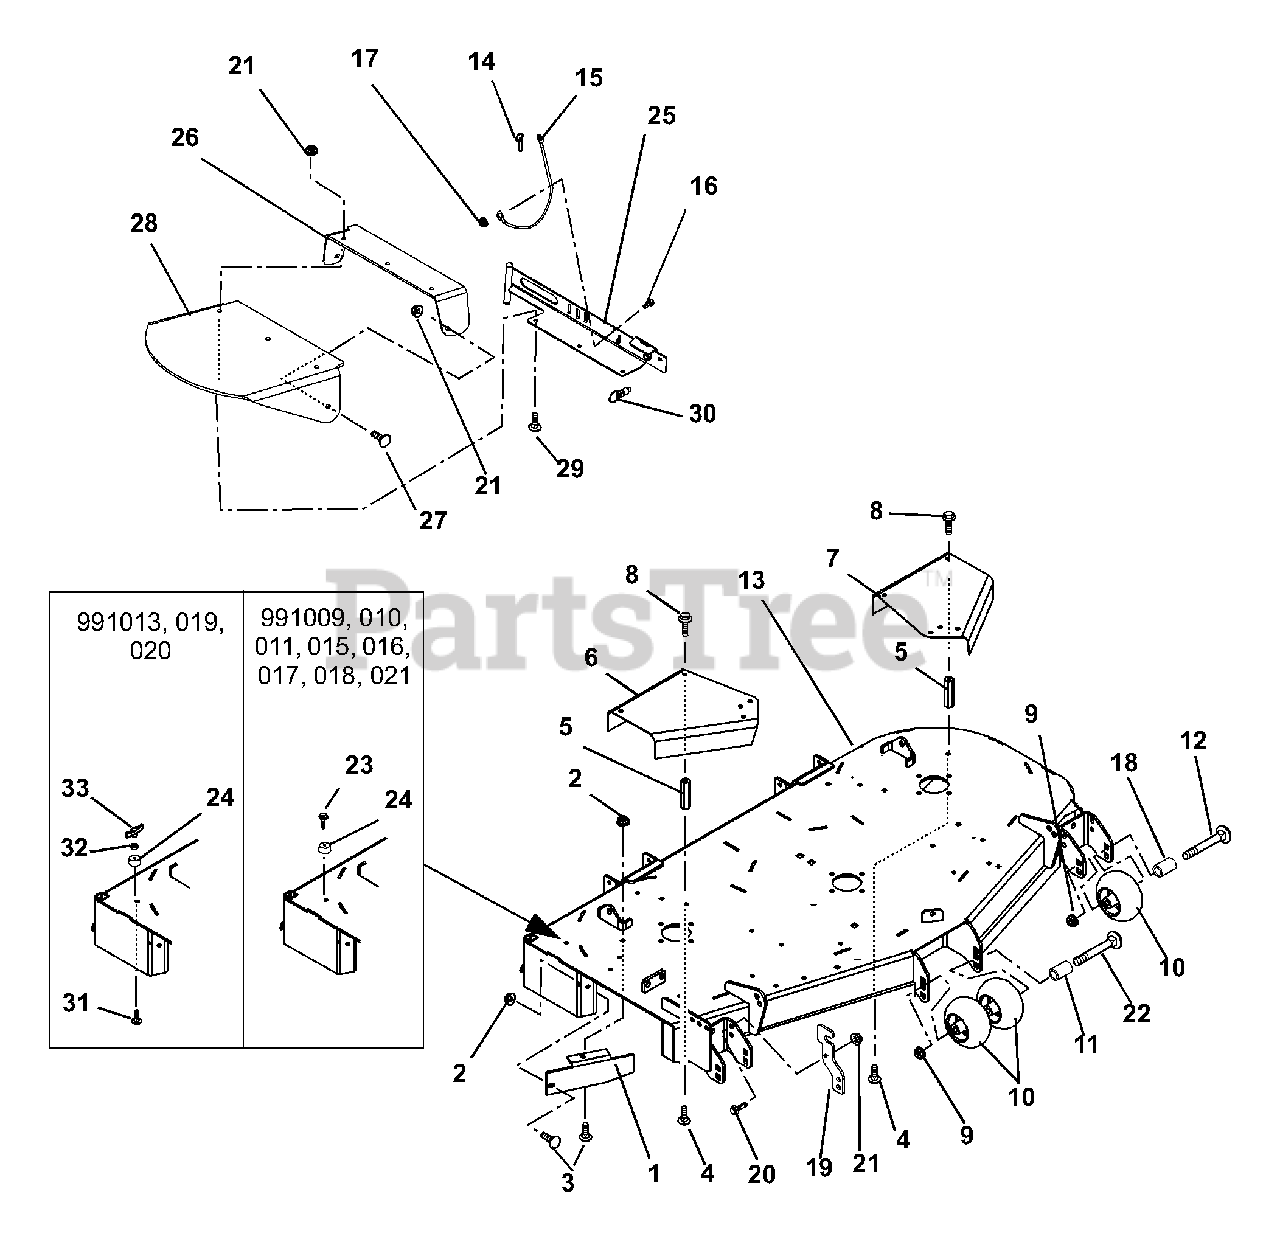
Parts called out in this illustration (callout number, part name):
1	44 in. & 48 in. Rear Discharge Baffle
1	52 in. Rear Discharge Baffle
1	60 in. Rear Discharge Baffle
2	Nut, .31-18 Nyloc Flange
3	Bolt, Round Head Square Neck .31-18 x 1.00 Grade 5
4	Bolt, Round Head Square Neck .31-18 x .75 Loctite with Epoxy Patch
5	Nut, Coupling .31-18 x 3.00
6	44 in. Right Hand Spindle Guard
6	48 in. & 52 in. Right Hand Spindle Guard
6	60 in. Right Hand Spindle Guard
7	44 in., 48 in., & 52 in. Left Hand Spindle Guard
7	60 in. Left Hand Spindle Guard
8	Bolt, SEMS .31-18 x .62
9	Nut .50-13 Nyloc Flange
10	Anti-Scalp Wheel
12	Bolt-Round Head Square Neck .50-13X5.00
13	44 in. Mower Deck
13	48 in. Mower Deck
13	52 in. Mower Deck
13	60 in. Mower Deck
14	Pin, Spring Ball .375 OD x 1.50
15	Cable, 5-in.
16	Bolt, Hex .25-20 x .75 Grade 5
17	Nut, Locking Top Flange .25-20
18	Spacer, .510 x .625 x 3.35
19	Chute, Storage Bracket
20	Bolt, Hex .38-16 x 1.00
21	Nut, .38-16 Nyloc Flange
22	Bolt, Round Head Square Neck .50-13 x 8.50
23	Screw, Tapping .31-18 x .75 Hex Washer Head Thread
24	Bumper, Recessed 1.50 x .63 , .31 Thru Hole
25	52 in. & 60 in. Discharge Chute Mounting Weldment
25	44 in. & 48 in. Discharge Chute Mounting Weldment
26	Rubber Discharge Chute Support
27	Bolt, Round Head Square Neck .38-16 x 1.00 Grade 5
28	Chute, Rubber Discharge
29	Bolt, Round Head Square Neck .38-16 x 1.25 Grade 5
30	Pin, Pull
31	Bolt, Round Head Square Neck .31-18 x 1.50 Grade 5
32	Nut, Locking Center .31-18
33	Knob, Wing .312-18
